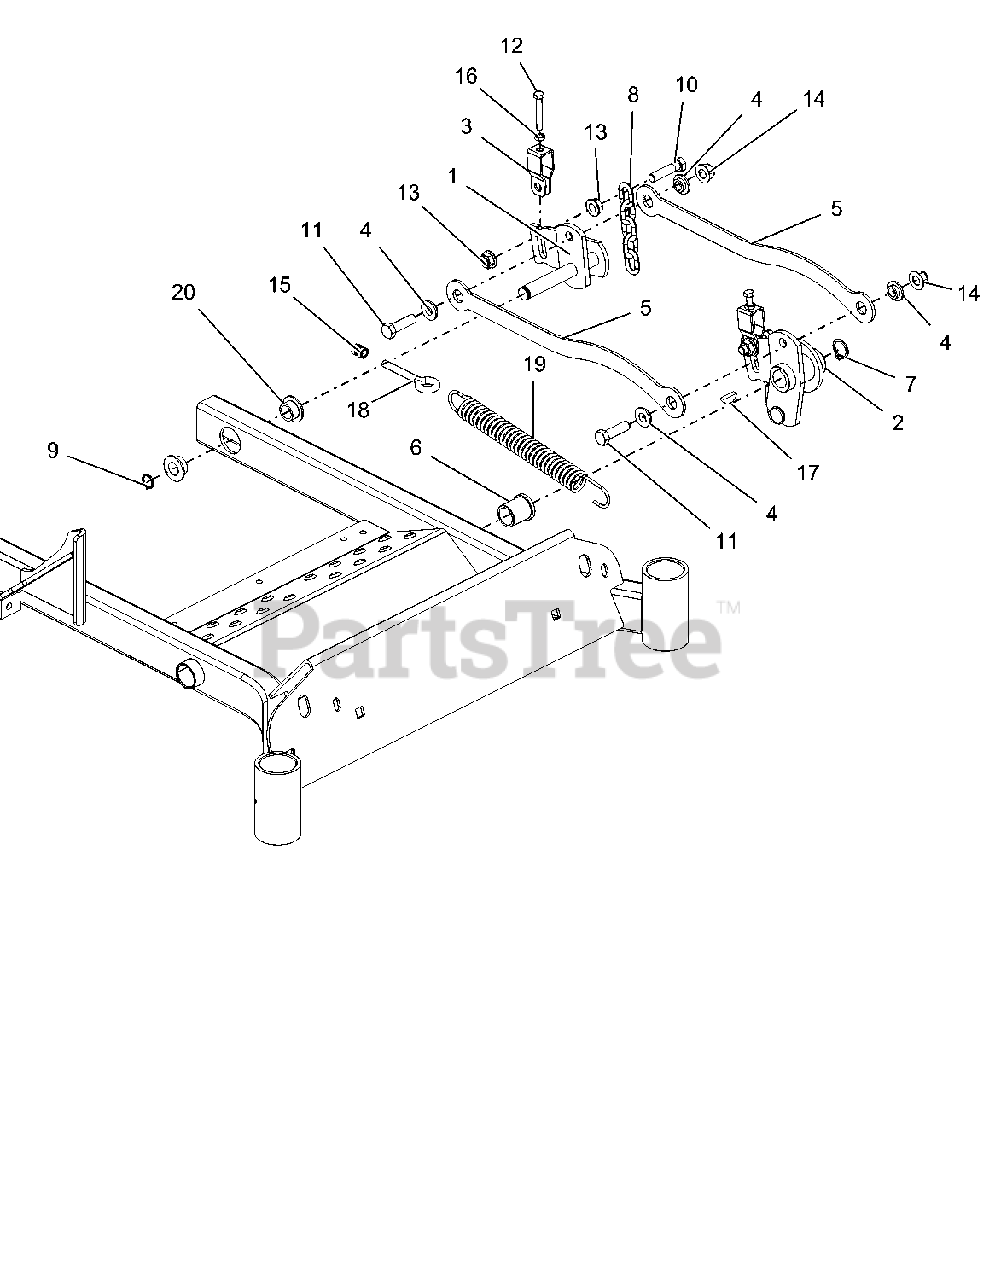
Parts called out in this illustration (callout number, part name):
1	WLDMT, REAR LH DECK LIFT ARM
2	WLDMT, FRONT LH DECK LIFT ARM
3	BRKT, DECK LEVELING
4	BSHG, FLANGE .515X.750X.31X1.12
5	LINK, LIFT - BLK
6	BSHG-FLG 1.00X1.25X1.5X1.5
7	RG-RTNG-EXT 1.00X.078
8	CHAIN, MOWER LIFT
9	RG-RTNG-EXT .750x.078
10	BLT, HEX M12-1.75X50 CLS8.8 YZ
11	BLT-HEX .50-13X1.75 GR5 YWZC
12	BLT-HEX .31-18X2.00 FTH GR5 YWZC
13	NUT, SPLK -FLG M12-1.75 YZ
14	NUT-LK-NYL-FLG .50-13 YWZC
15	NUT, JAM .375-16 YWZC
16	NUT, JAM .312-18 YWZC
17	KEY, WDRF .25 X 1.00 HRD #15
18	BOLT, EYE .375-16
19	SPRG, TENSION .162 X 1.250 X 8.250
20	BSHG, FLANGED .762X1.0X.580X1.48 NY
